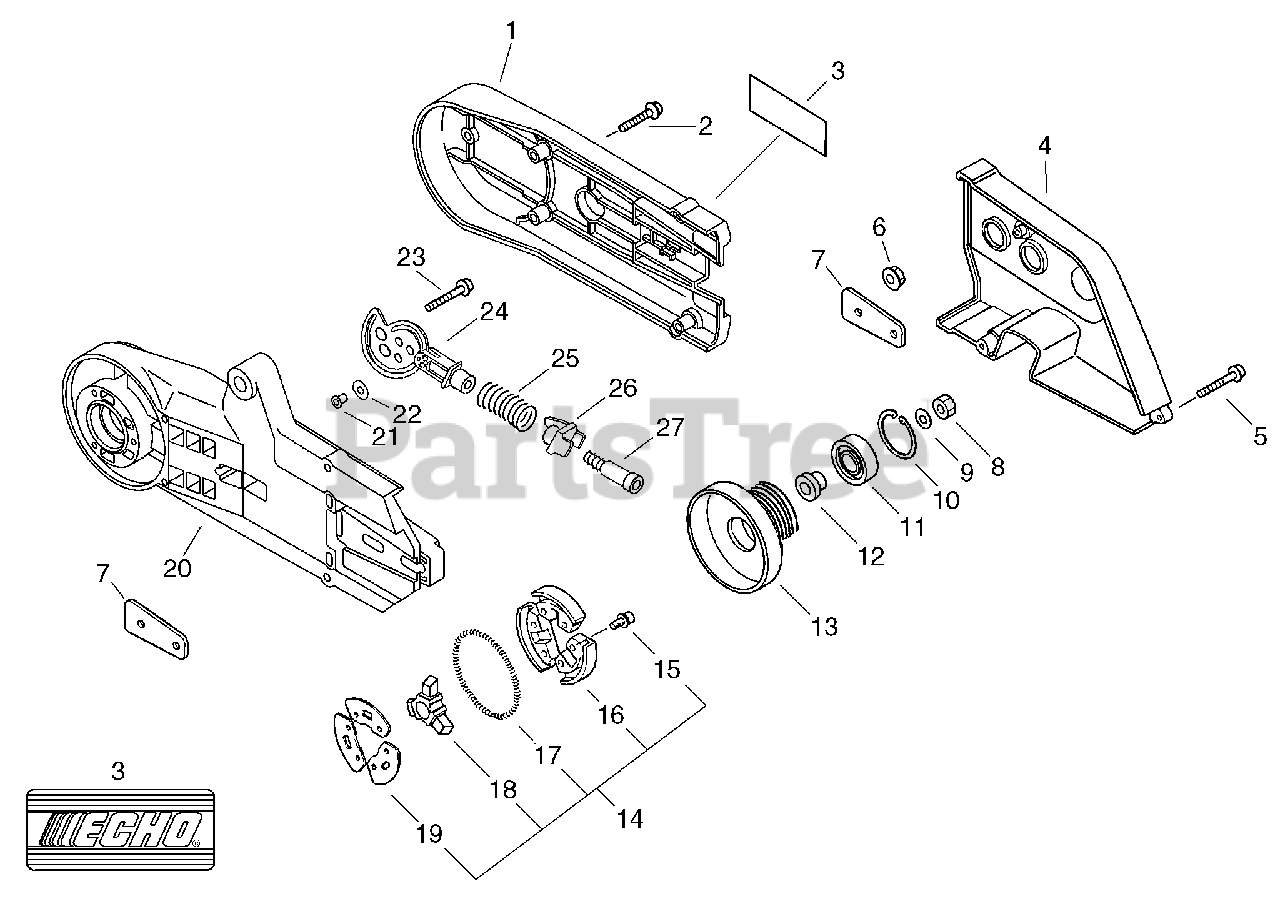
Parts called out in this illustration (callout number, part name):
1	COVER, CUTTER ARM
2	SCREW - 5X25
3	LABEL - ECHO
4	COVER, V-BELT
5	SCREW - 5X25
6	NUT - 8 -- FLANGE
7	SPACER, ARM
8	NUT - 8 -- LEFT HAND
9	WASHER - 8
10	RING, RETAINING - 28
11	BEARING, BALL - 6001 DDU
12	COLLAR - 10
13	DRUM, CLUTCH
14	CLUTCH ASSY
15	SCREW - 4X6
16	CLUTCH SHOE SET
17	SPRING, CLUTCH
18	HUB, CLUTCH
19	PLATE, CLUTCH
20	ARM, CUTTER
22	WASHER - SPRING
23	SCREW - 5X25
24	ADJUSTER
25	SPRING, ADJUST
26	SEAT, SPRING
27	SCREW - 5
